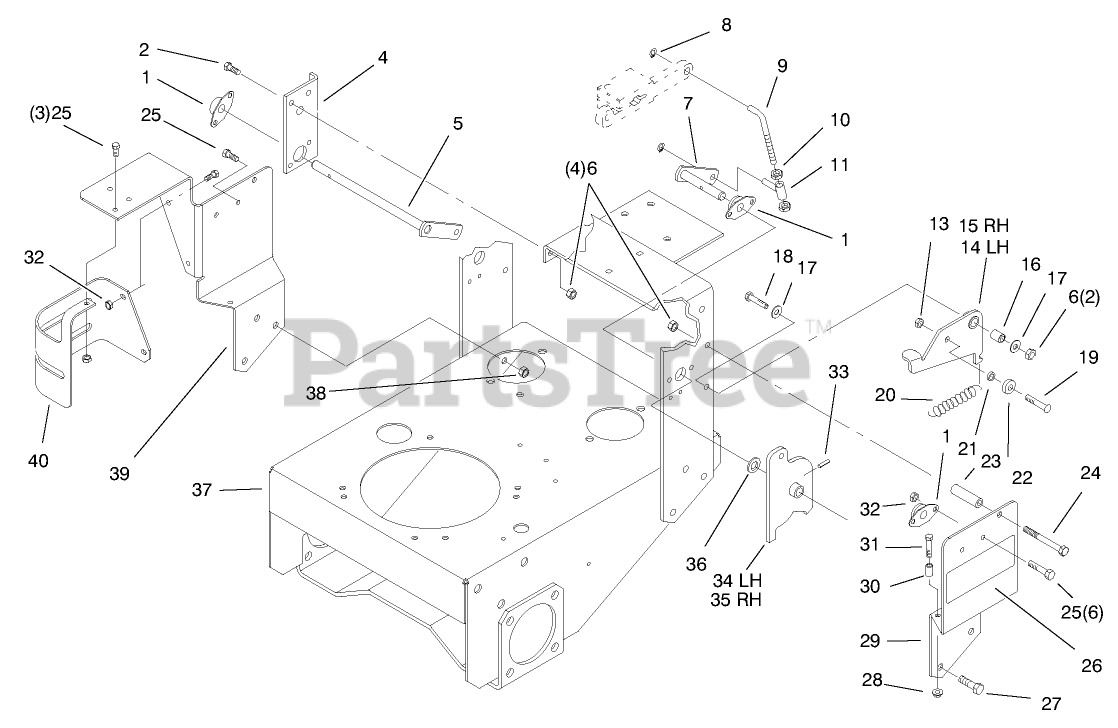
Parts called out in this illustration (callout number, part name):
1	SIDE FLANGE BEARING ASM
2	SCREW-HH
4	BRACKET-BUSHING
5	LEVER-PIVOT, RH
6	NUT-LOCK, NI
7	LEVER-PIVOT, LH
8	RING-GRIP
9	ROD-LINK
10	NUT-JAM
11	SLEEVE
13	NUT-LOCK, NI
14	ARM-DETENT, LH
15	ARM-DETENT, RH
16	BUSHING-ARM, DETENT
17	WASHER-PLAIN
18	SCREW-HH
19	SCREW-HSBH
20	SPRING-DETENT
21	SPACER-BEARING
22	BEARING-BALL
23	STOP-REVERSE
24	SCREW-HH
25	SCREW-HH
26	DECAL-HYDRO
27	SCREW-HH
28	NUT-LOCK, HHF
29	BRACKET-PIVOT, LH
30	SPACER-TUBULAR
31	SCREW-HH
32	NUT-LOCK, NI
33	PIN-ROLL, SLOTTED
34	ARM-PIVOT, LH
35	ARM-PIVOT, RH
36	WASHER-THRUST
37	FRAME WA
38	NUT-LOCK, NI
39	BRACKET-PIVOT, RH
40	GUARD-FILTER
